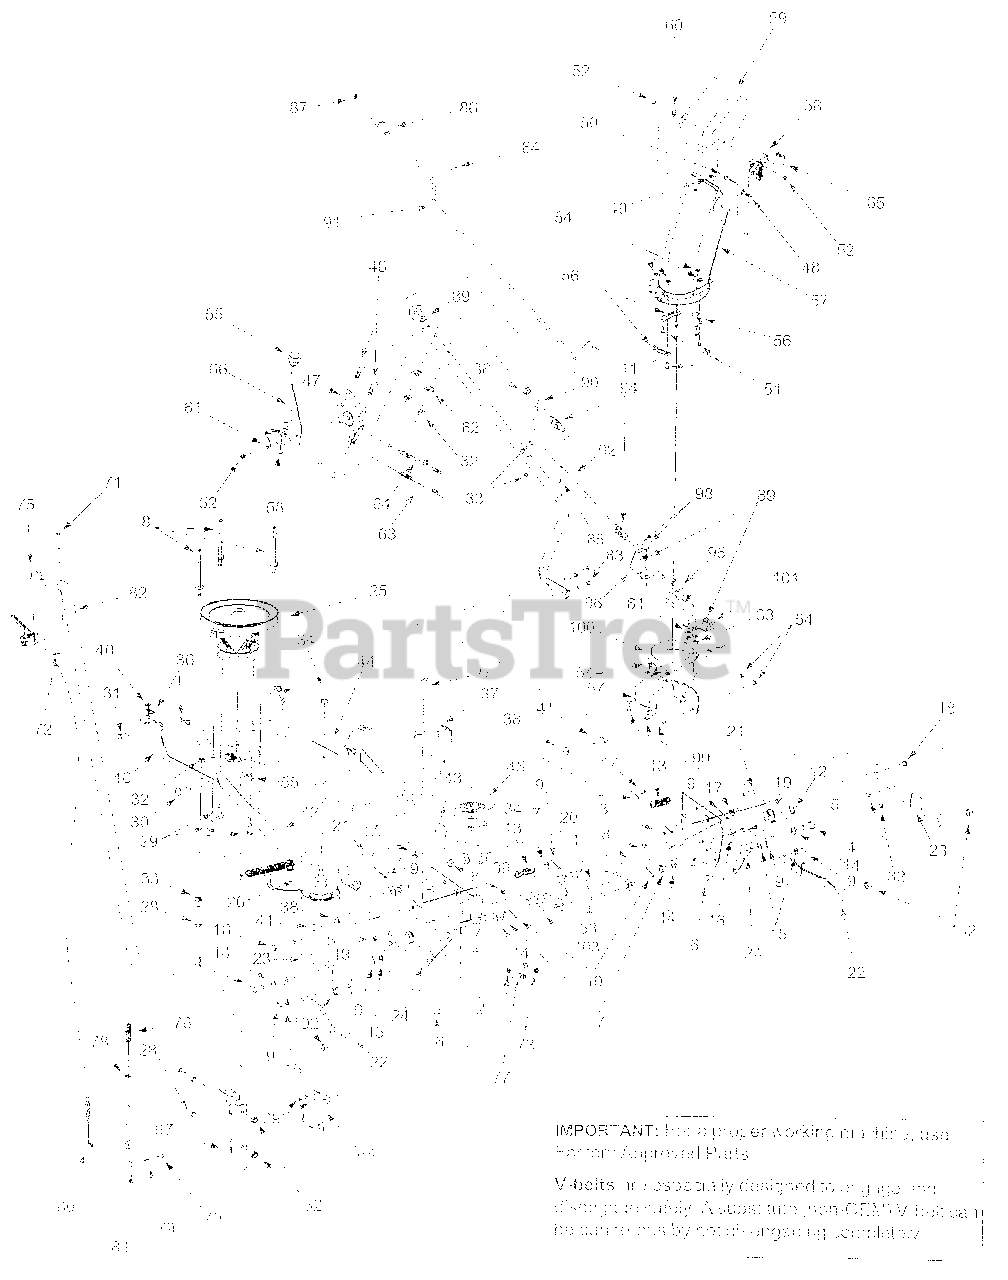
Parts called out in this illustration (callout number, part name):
2	RH Support Plate Assembly
3	LH Support Plate Assembly
4	Hex Cap Screw, 5/8-18 x 1.31
5	Hex Cap Screw, 3/8-16 x 1.0
6	Clevis Pin, .5 x .78
7	Slotted Hex Nut, 5/8-18
8	Belt Keeper Pin
9	Cotter Pin, .125 x .75
10	Cotter Pin, 1/8 x 1.25
11	Cotter Pin
12	Snap Ring
13	Compression Spring, .72 x 2.25
14	Flat Washer, .64 x 1.12 x .125
15	Flat Washer, .51 x 1.0 x .060
16	Bell Washer, .396 x 1.14 x .095
17	Flat Washer, .531 x .875 x .15
18	Shoulder Screw, .5 x .29, 3/8-16
19	Flange Bearing w/ Flats
20	Rod, 1/2 x 11.55
21	Handle Rod
25	Spindle Assembly
26	Double-idler Bracket Assembly
27	Hex Cap Screw, 3/8-16 x 1.75
28	Hex Cap Screw, 5/16-18 x 1.75
29	Self Tapping Screw, 5/16-18 x .75
30	Clevis Pin, .5 x 1.18
31	Clevis Pin, 3/8 x .75
32	Flange Lock Nut, 5/16-18
33	Hex Nut, 5/16-18
34	Hex Flange Lock Nut, 3/8-24
36	Click Pin, .092 x 1.64
37	Belt Guard
38	Flat Washer, .531 x .93 x .09
39	Flat Washer, .38 x .93 x .11
40	Flat Washer, .344 x .688 x .065
41	Shoulder Screw, 3/8-16, .5 x .835,
44	Upper V-belt
45	Idler Pulley, 3.5" Diameter
46	Pulley Mounting Bracket
48	Carraige Bolt, 5/16-18 x 1.5
49	Carraige Bolt, 5/16-18 x .75
50	Hex Index Washer Screw, 1/4-14 x .625
51	Hex Cap Screw, 1/4-20 x .75
52	Nylon Hex Lock Nut, 5/16-18
53	Hex Cap Screw, 5/16-18 x .75
54	Hex Flange Lock Nut, 1/4-20
55	Knob
56	Chute Flange Keeper
57	Lower Chute
58	Chute Tilt Cable Guide
59	Upper Chute
60	Flat Washer, .344 x 1.125 x .125
61	Bell Washer, .34 x .872
62	Saddle Washer, .32 x .93
63	Chute Cable, 62"
64	Chute Cable w/ Clip, 62"
70	Hex Index Washer Screw #10-16 x .375
71	Pan Phillips Screw, #10-24 x .75
72	Flat Weld Nut, #10-24
73	Hex Nut, 5/16-24
75	Handle Grip
76	Compression Spring, .406 x .531 x 1.75
77	Lock Washer, 5/16
78	Flat Washer, .385 x .62 x .063
79	Flat Washer, .194 x .62 x .063
80	Lift Cable, 42" w/ Trigger Control
81	Lift Index Rod
83	Hex Cap Screw, 5/16-18 x 1.5
84	Rolled Pin, 1/8 x .63
85	Spirol Pin, .125 x .82
86	Crank Knob
87	Push Cap, 3/8 ID
88	Rubber Grommet , .44 x .94 x .5
89	Plastic Bushing
90	Eye Bolt
91	Chute Crank Rod, .375 x 33
92	Rod, .375 x 11.375
94	Joint Block Assembly
95	Chute Crank Assembly
98	Splined Carriage Screw, 5/16-18 x 1.0
99	Carriage Screw, 1/4-20 x .5
100	Adapter Chute
102	Hex Lock Nut, 1/2-13
103	Heat Shield
